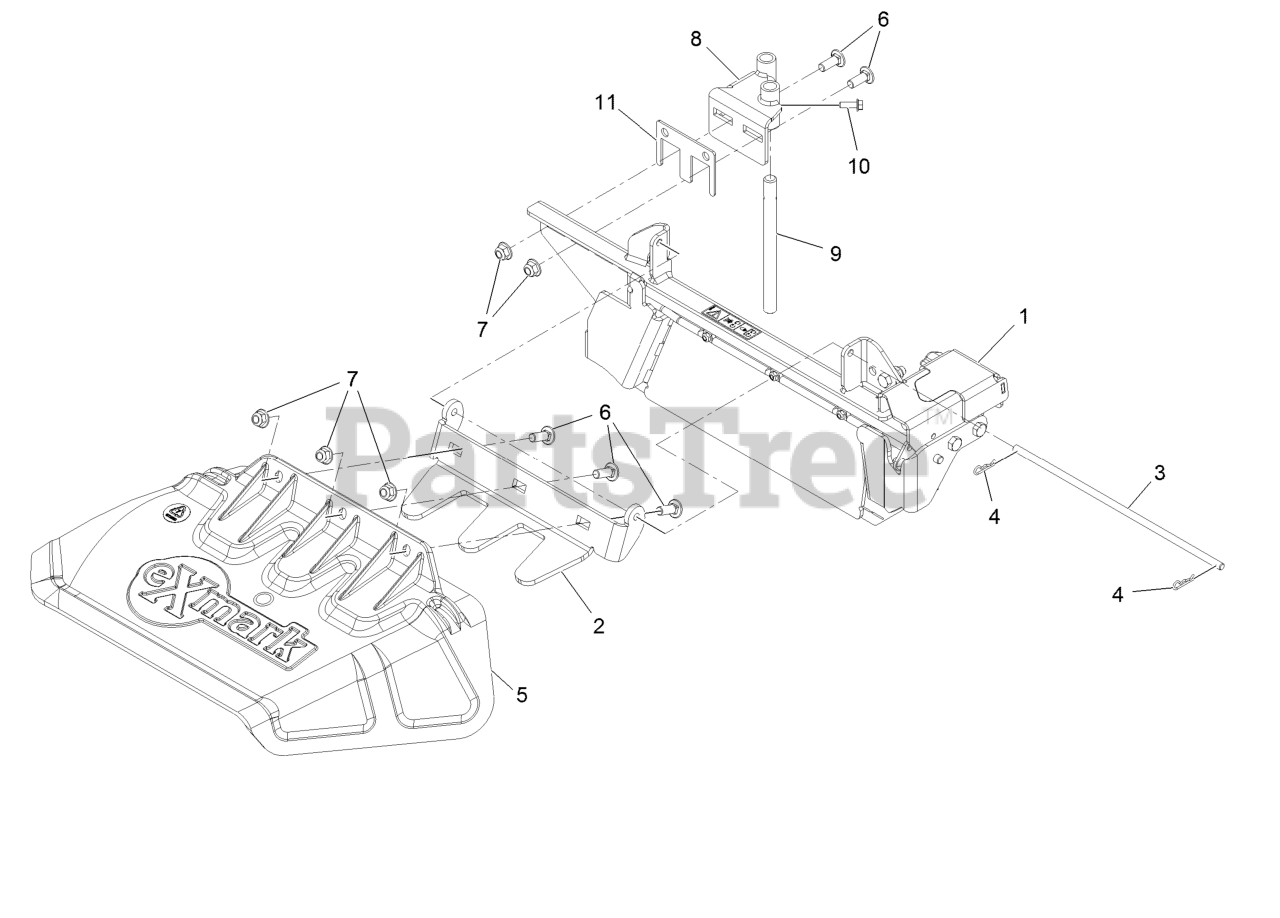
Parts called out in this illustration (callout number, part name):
1	ASM, Ocd Gate
2	Mount, Discharge Chute
3	Pin,Chute
4	Hairpin-Cotter
5	Chute, Discharge
6	Bolt-Carriage 3/8-16 X 1
7	Nut-Nyloc 3/8-16 Flg
8	Weldment, Ocd Mount
9	Pin-Mount, Ocd
10	Screw-Hex Flange 1/4-20 X 3/4
11	Shim-Ocdwb
